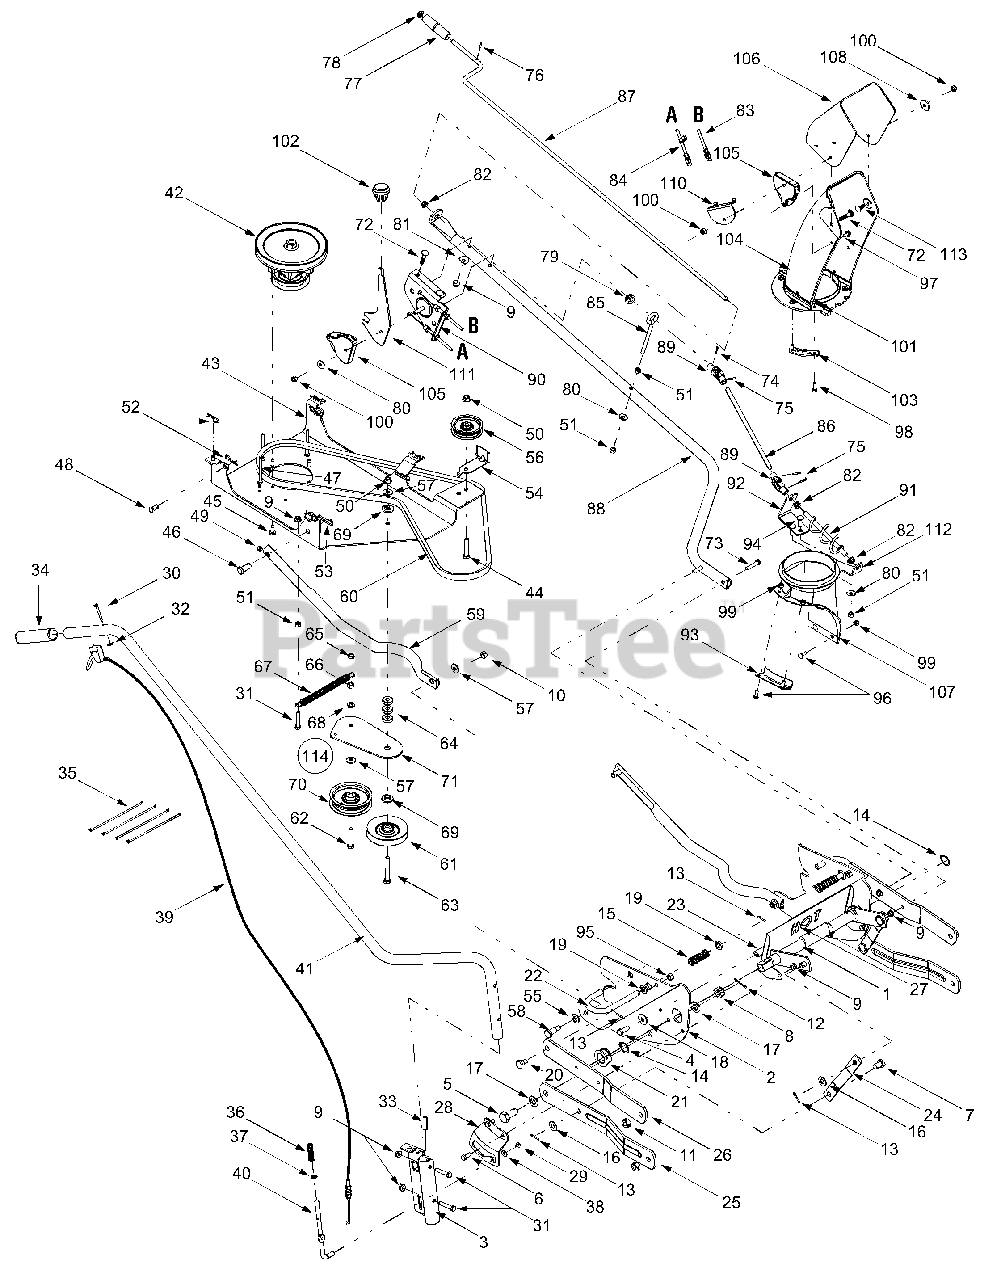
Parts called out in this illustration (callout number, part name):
2	RH Support Plate Assembly
5	Hex Cap Screw, 5/8-18 x 1.31
6	Hex Cap Screw, 5/16-18 x .75
7	Clevis Pin, .5 x .78
8	Slotted Hex Nut, 5/8-18
9	Flange Lock Nut, 5/16-18
10	Hex Nut, 3/8-16
11	Hex Lock Nut, 1/2-13
12	Cotter Pin, 1/8 x 1.25
13	Cotter Pin, .125 x .75
14	Snap Ring
15	Compression Spring, .72 x 2.25
16	Flat Washer, .51 x 1.0 x .060
17	Flat Washer, .64 x 1.12 x .125
18	Bell Washer, .396 x 1.14 x .095
19	Flat Washer, .531 x .875 x .15
20	Shoulder Screw, .5 x .29, 3/8-16
21	Flange Bearing w/ Flats
22	Handle Rod
23	Rod, 1/2 x 11.55
27	Heat Shield
30	Pan Phillips Screw, #10-24 x .75
31	Hex Cap Screw, 5/16-18 x 1.75
32	Flat Weld Nut, #10-24
33	Heavy Duty Spirol Pin, 1/4 x 1.5
34	Handle Grip
35	Cable Tie
36	Compression Spring, .406 x .531 x
37	Flat Washer, .385 x .62 x .063
38	Flat Washer, .194 x .62 x .063
39	Lift Cable, 42" w/ Trigger Control
40	Lift Index Rod
42	Spindle Assembly
43	Pulley Mounting Bracket
44	Hex Cap Screw, 3/8-16 x 1.75
45	Self Tapping Screw, 5/16-18 x .75
46	Clevis Pin, .5 x 1.18
47	Belt Keeper Pin
48	Clevis Pin, 3/8 x .75
49	Hex Lock Nut, 1/4-20
50	Hex Flange Lock Nut, 3/8-24
51	Hex Nut, 5/16-18
52	Click Pin, .092 x 1.64
53	Internal Cotter Pin, .125 x 1.75
54	Belt Guard
55	Flat Washer, .531 x .93 x .09
56	Idler Pulley, Flat 2.75 OD
57	Flat Washer, .38 x .93 x .11
58	Shoulder Screw, 3/8-16, .5 x .835,
60	Upper V-belt
61	Idler pulley, 4" Diameter
62	Hex Cap Screw, 3/8-24 x 2
63	Hex Cap Screw, 3/8-16 x 3
64	Spacer
65	Nylon Jam Lock Nut, 3/8-24
66	Hex Nut, 3/8-24
67	Extension Spring, .620 x 5.62
68	Lock Washer, 3/8
69	Shoulder Spacer, .625 x .169
70	Idler Pulley, 3.5" Diameter
72	Carriage Bolt, 5/16-18 x 1.5
73	Hex Cap Screw, 5/16-18 x 1.5
74	Cotter Pin, 3/32 x .75
75	Spiral Pin, .125 x .82
76	Rolled Pin, 1/8 x .63
77	Crank Knob
78	Push Cap, 3/8 ID
79	Rubber Grommet , .44 x .94 x .5
80	Bell Washer, .34 x .872
81	Saddle Washer, .32 x .93
82	Plastic Bushing
83	Chute Cable, 62"
84	Chute Cable w/ Clip, 62"
85	Eye Bolt
86	Rod, .375 x 11.375
87	Chute Crank Rod, .375 x 33
88	Support Chute Tube
89	Joint Block Assembly
91	Chute Crank Assembly
94	Splined Carriage Screw, 5/16-18 x 1.0
95	Hex Lock Nut, 3/8-16
96	Screw, 1/4-20 x .75
97	Hex Index Washer Screw, 1/4-14 x
98	Hex Cap Screw, 1/4-20 x .75
99	Nylon Hex Lock Nut, 1/4-20
100	Nylon Hex Lock Nut, 5/16-18
101	Hex Flange Lock Nut, 1/4-20
102	Knob
103	Chute Flange Keeper
104	Lower Chute
105	Chute Tilt Cable Guide
106	Upper Chute
107	Adapter Chute
108	Flat Washer, .344 x 1.125 x .125
113	Carriage Screw, 5/16-18 x 1.0
114	Double Idler Assembly
